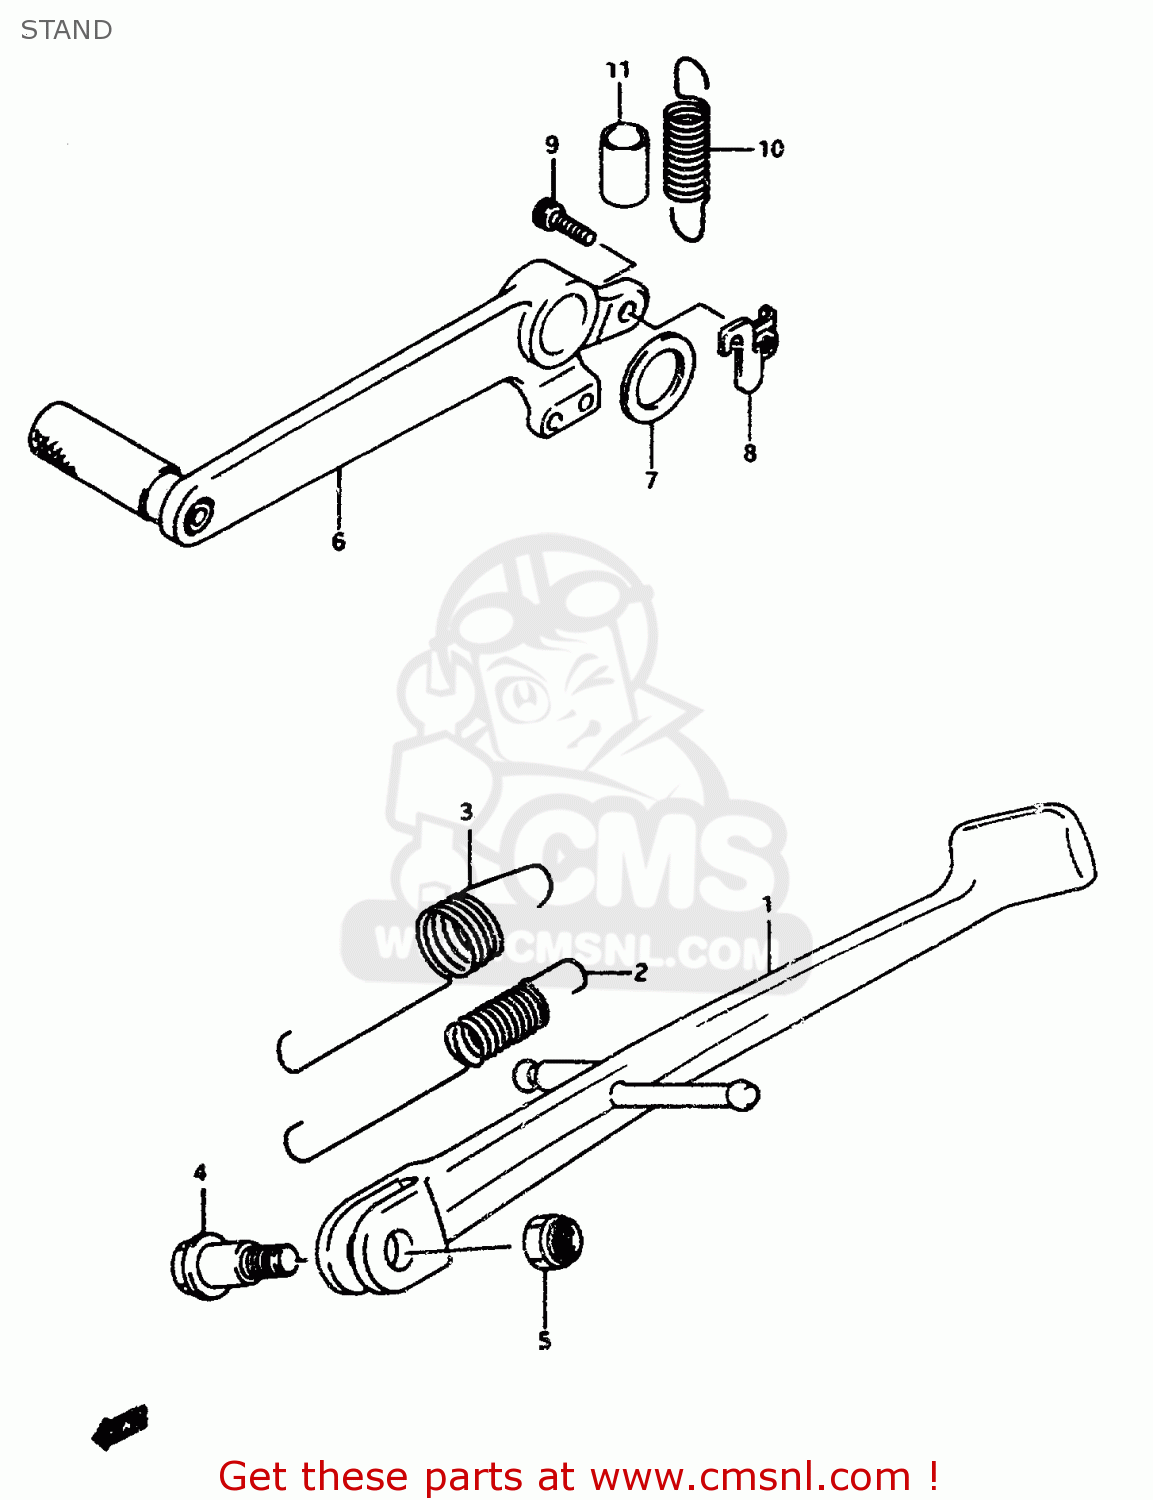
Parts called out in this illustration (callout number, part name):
1	STAND,PROP
2	SPRING
3	SPRING
4	BOLT(10X30)
5	NUT
6	PEDAL,BRAKE
7	WASHER
8	BRACKET,STOP LAMP SWITCH SPR
9	BOLT
10	SPRING
11	TUBE,BRAKE SPRING GUIDE
